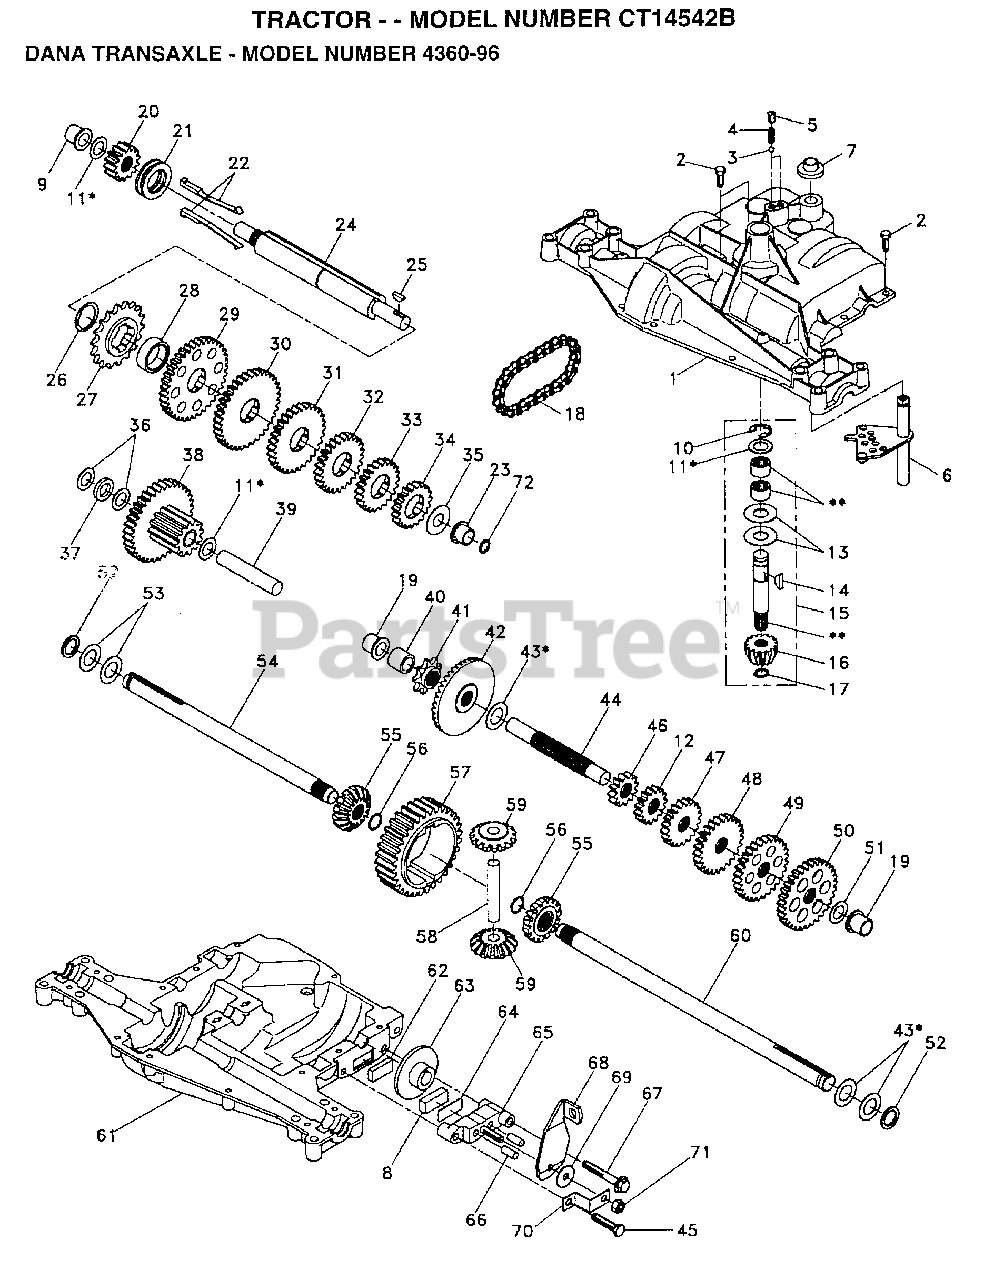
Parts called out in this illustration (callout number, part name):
1	HARNESS.IGNITION
4	"SPRING, DETENT LT"
5	"SCREW, SET LT"
6	KIT SHIFTER ASM
7	SHIFTER BOOT
8	PUCK T
10	RETAINING RING LT
11	ASM KIT SHIM 4689
12	PLUG.PLASTIC
13	WASHER T
14	KEY WOODRUFF-DANA
16	BELT-V.79.1.MWR
17	"RING,RETAINING LT"
18	"CHAIN,24 PTCH LT"
19	BEARING.FLNG.5510
20	GEAR SPUR 14 TTH
21	CLUTCH.COL.5467
22	KIT.ASM.CLUTCH KY
23	BEARING.FLNG.5511
24	SHAFT INTERM DANA
25	WOODRUFF KEY
26	"RING,RETAINING LT"
27	SPROCKET 18T T
28	SPACER YT
29	GEAR SPUR 37 TTH
30	GEAR SPUR 35 TTH
31	GEAR SPUR 30T
32	GEAR 25T LT
33	GEAR SPUR 22 TT
34	SPUR GEAR 19T
35	"WASHER, PLAIN LT"
36	WASHER 025
37	SPACER
38	ASSM GEAR COMB
39	SHAFT IDLER
40	SPACER T
41	SPROCKET 9T LT
43	ASM KIT SHIM
44	SHAFT T
45	"SCREW, TAPPING LT"
46	GEAR SPUR 12 TTH
48	"GEAR, SPUR 25T LT"
49	GEAR 28T T
50	"GEAR, SPUR 31T LT"
51	WASHER 060
52	NEOPRENE WASHER
53	WASHER 031
55	GEAR 15T T
56	"RING,RETAINING LT"
58	SHAFT T
59	GEAR 1ST T
61	HOUSING LOWER TNS
62	PUCK T
63	BRAKE DISC. T
64	SPACER LT
66	PIN T
69	WASHER LT
71	NUT.LOCK.5/16-24
72	SEAL.OIL.DAN.5508
